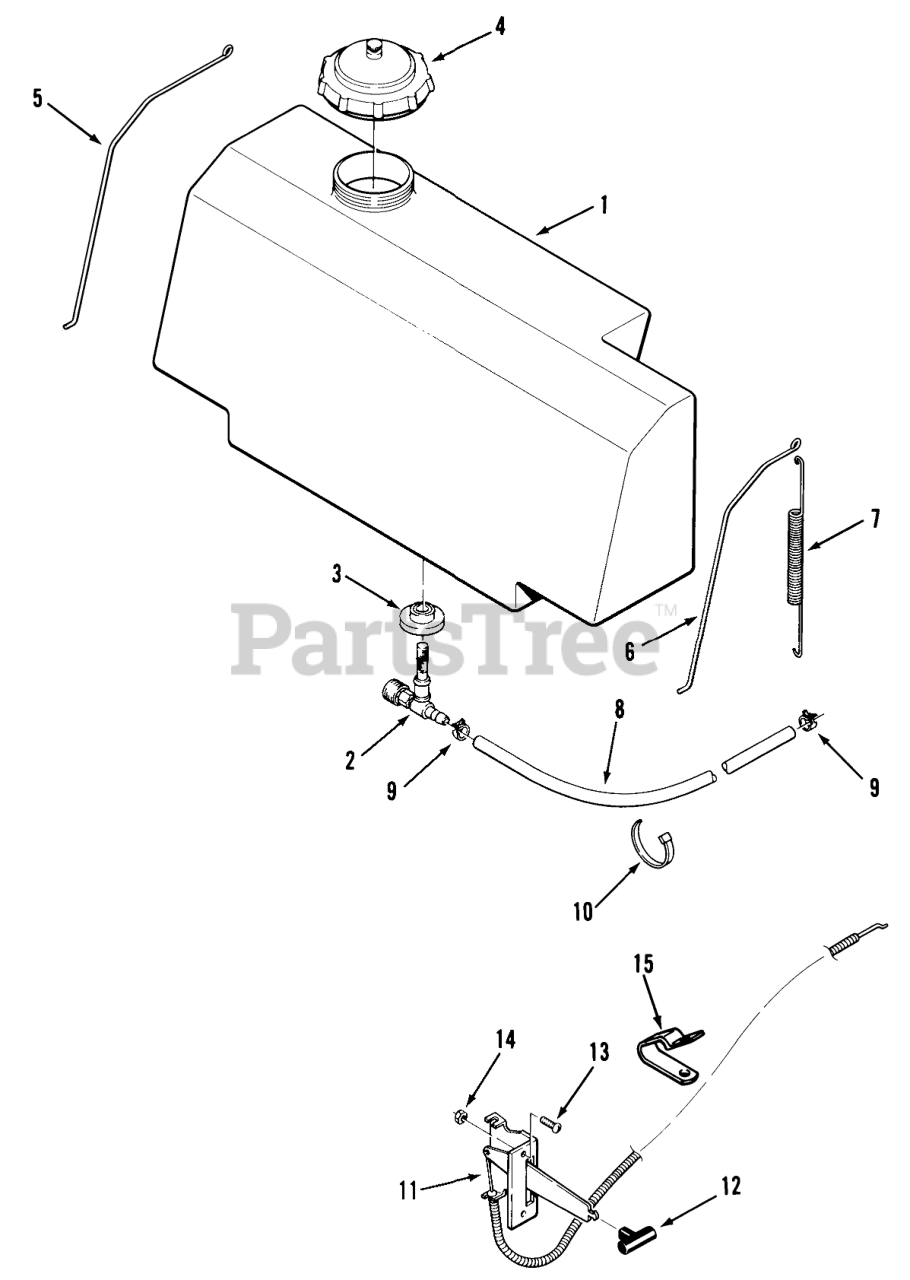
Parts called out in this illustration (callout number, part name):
1	FUEL TANK ASSY
2	VALVE-FUEL
3	BUSHING
4	ASSY FUEL CAP
5	RETAINER TANK RH
6	RETAINER TANK LH
7	SPRING EXTENSION
8	Hose
9	Clamp
10	PLASTIC TIE
11	CONTROL-THROTTLE
12	KNOB-CONTROL
13	Screw
14	Nut
15	CLAMP DOUBLE
